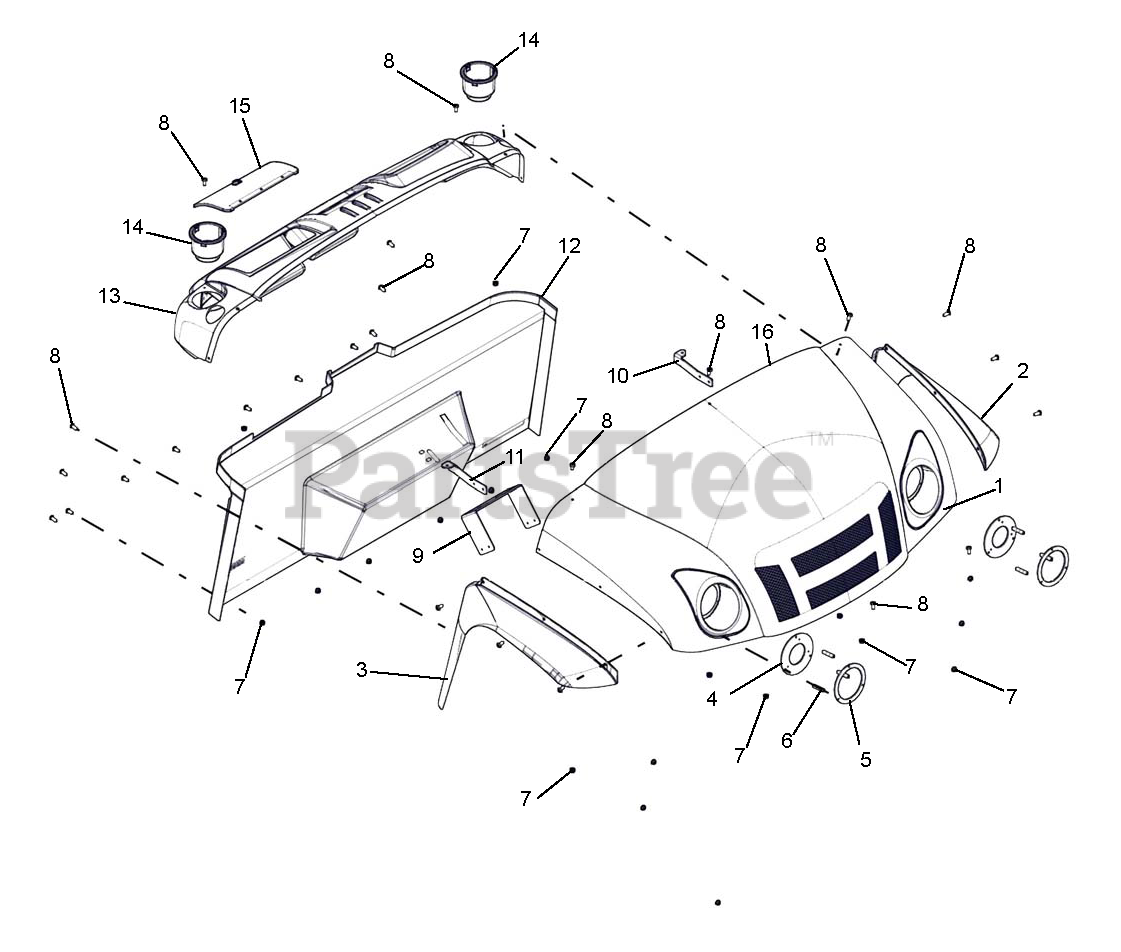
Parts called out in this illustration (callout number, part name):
1	KIT, HOOD W/DECALS
2	FENDER, FRONT, LH
3	FENDER, FRONT, RH
4	TOP FLANGE, HEADLIGHT
5	BASE FLANGE, HEADLIGHT
6	SPACER, HEADLIGHT
7	NUT HEX FLG TL 1/4-20 ZNYCR
8	TTHMS 1/4-20X1 ZNYCR
9	BRACKET,MNT,SWITCH
10	BRACKET,MNT,CUPHOLDER,LH
11	BRACKET, MNT,CUP HOLDER
12	KIT, FOOTWELL W/DECALS
13	DASH, ASM W/DECALS 4X2
14	CUPHOLDER, SNAP-IN 3.75OD
15	DOOR, GLOVEBOX NO LOGO
16	TRIM, 1/8 RUBBER EDGE(PER FT)
